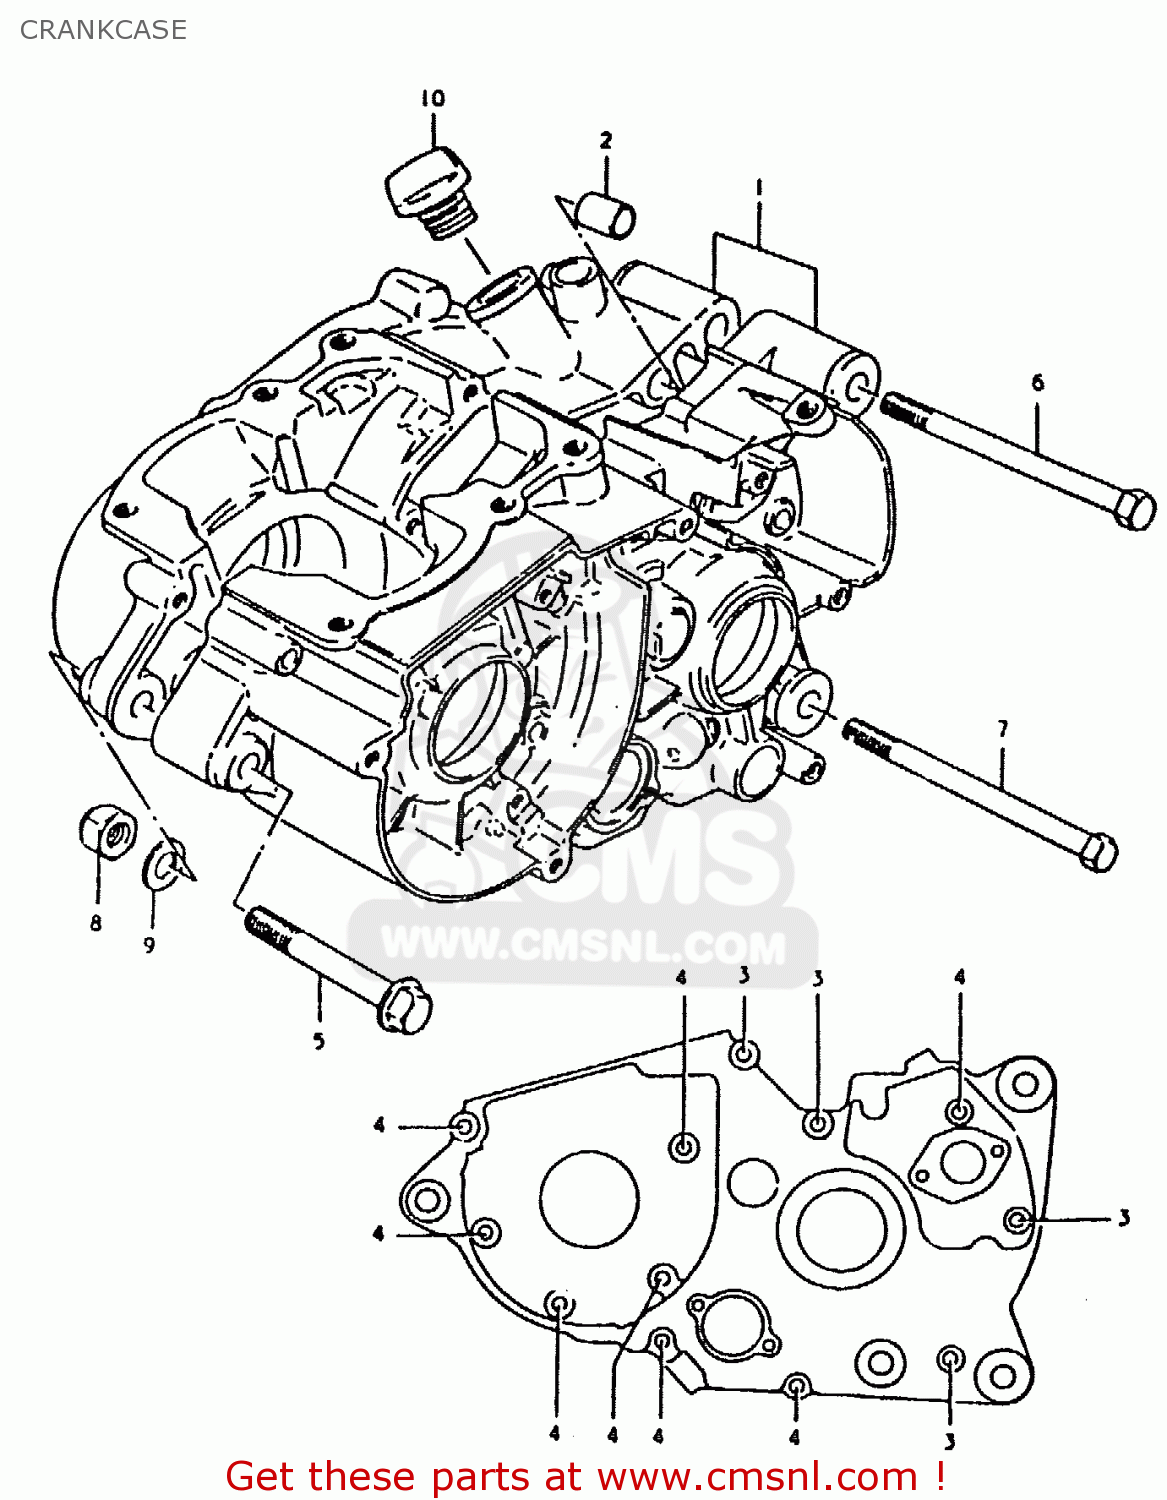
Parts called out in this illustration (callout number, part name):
1	CRANKCASE ASSEMBLY
2	PIN
3	SCREW
4	SCREW 6X60
5	BOLT (10X75)
6	BOLT(10X110)
7	BOLT
8	NUT
9	WASHER
10	PLUG
